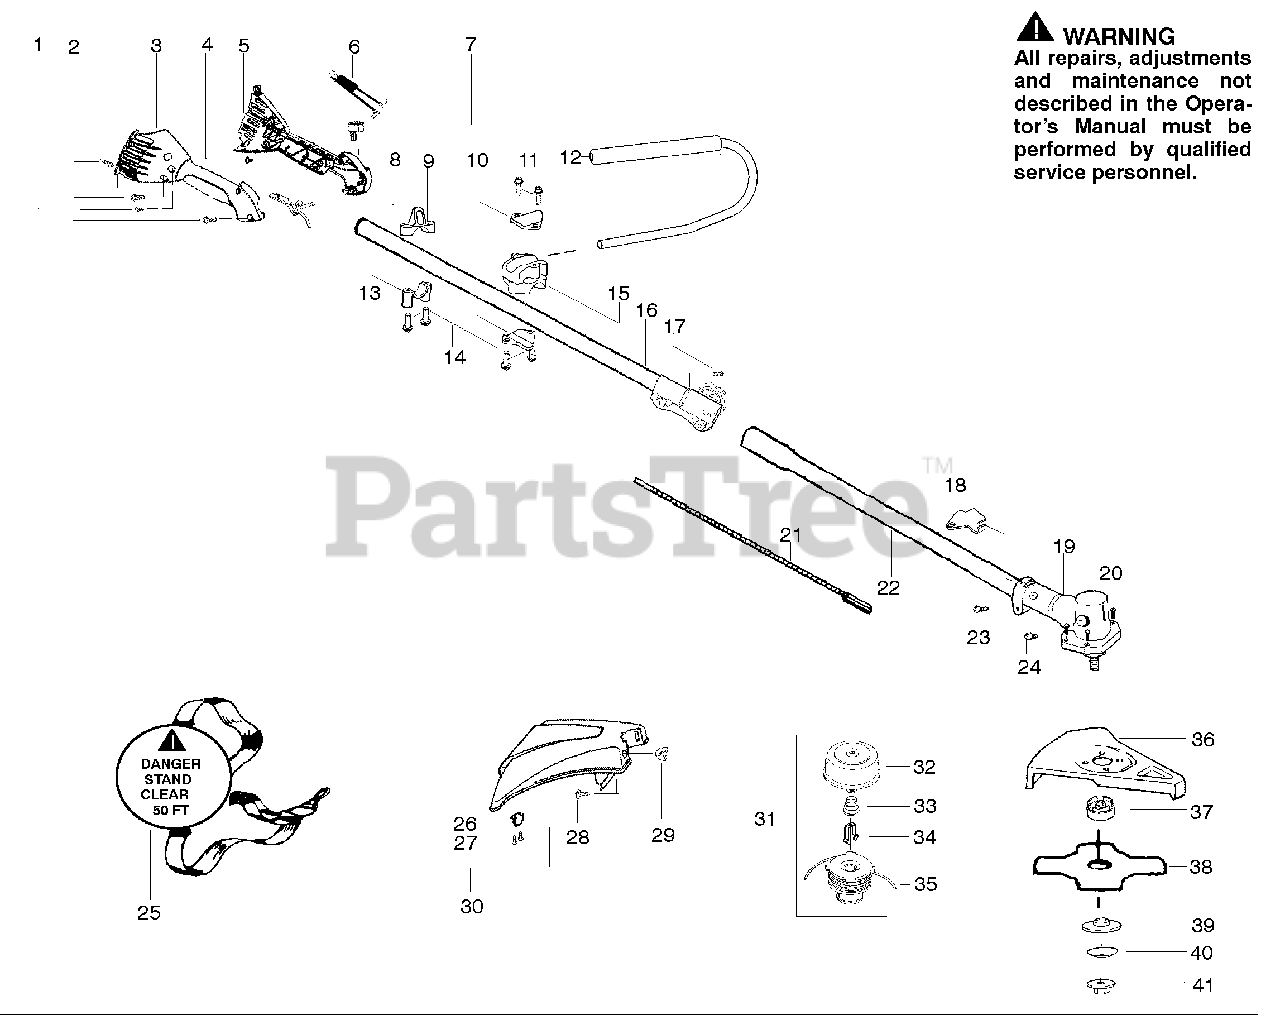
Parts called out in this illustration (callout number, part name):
1	Screw-alignment
3	Hsg.-Throttle-right
4	Screw-Cable Retention
5	Hsg.-Throttle-left
8	Trigger-Throttle
9	Clamp-Harness (upper)
10	Clamp-Bracket
12	Assy.-Handlebar
13	Clamp-Harness (lower)
15	Clamp-Handlebar
16	Kit-Upper Shaft
18	Bracket-Shield
21	Shaft-Flex (lower)
22	Assy-Lower Shaft
25	Shoulder Strap
29	Wingnut
30	Kit-Shield Assy.
31	Accy-Cutting Head
32	Assy-Hub/Arbor
33	Spring-Return
34	Retainer-Spool
35	Accy-Wound Spool
36	Kit-Metal Shield
38	Accy.-Weed Blade
40	Washer-Belleville
